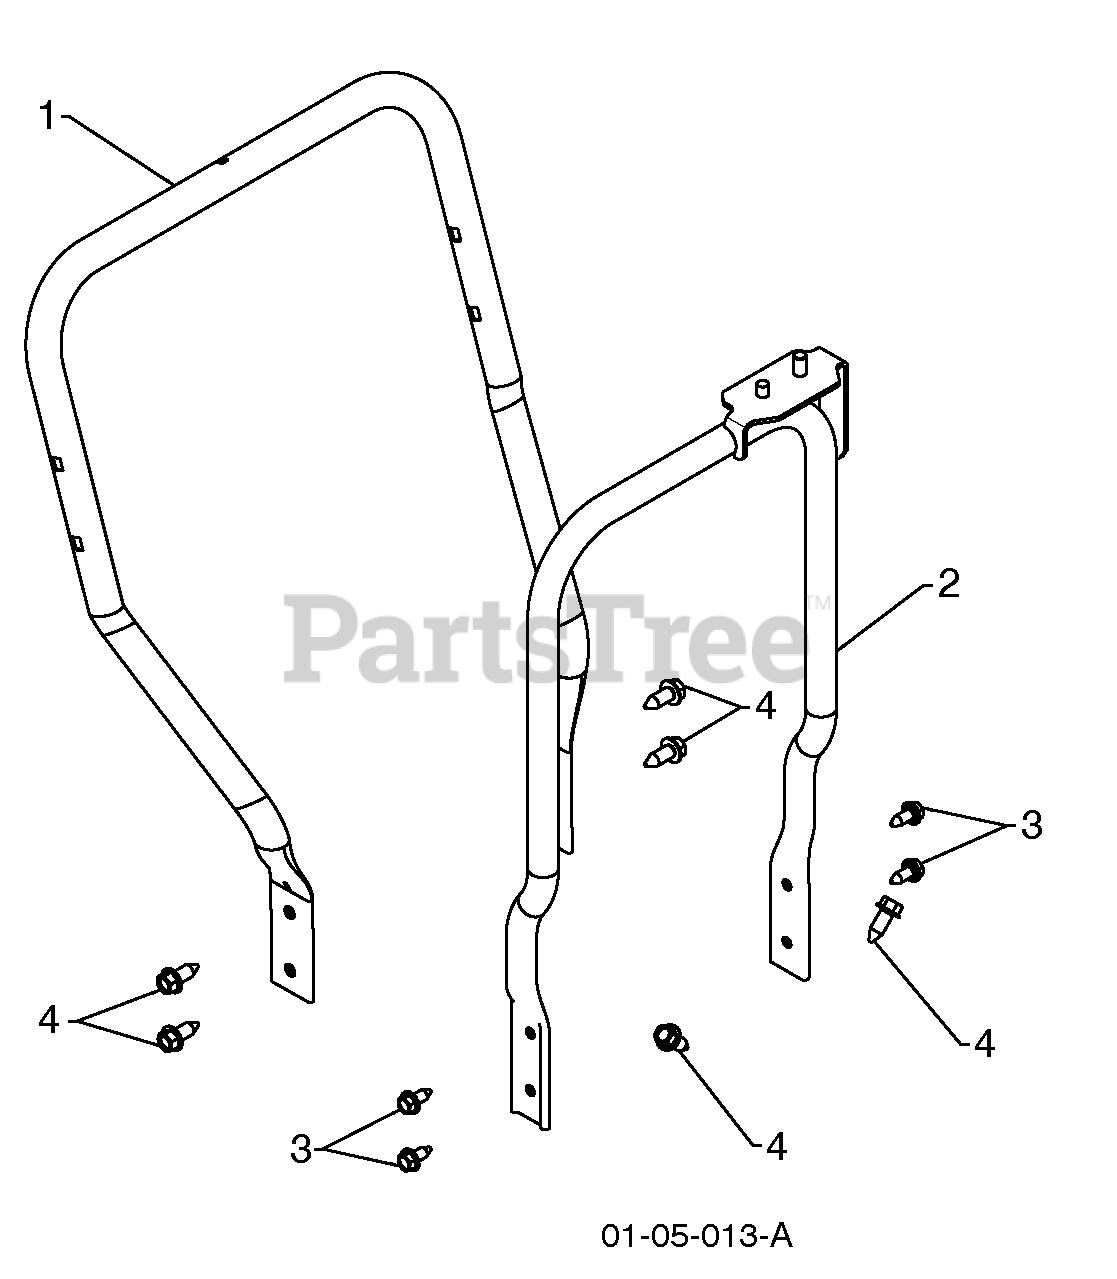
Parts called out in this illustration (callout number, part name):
1	LOWER HANDLE
2	PIVOT SUPPORT WELDMENT
3	SCREW 5/16-18 X .750
4	SCREW 3/8-16 X 1.00
